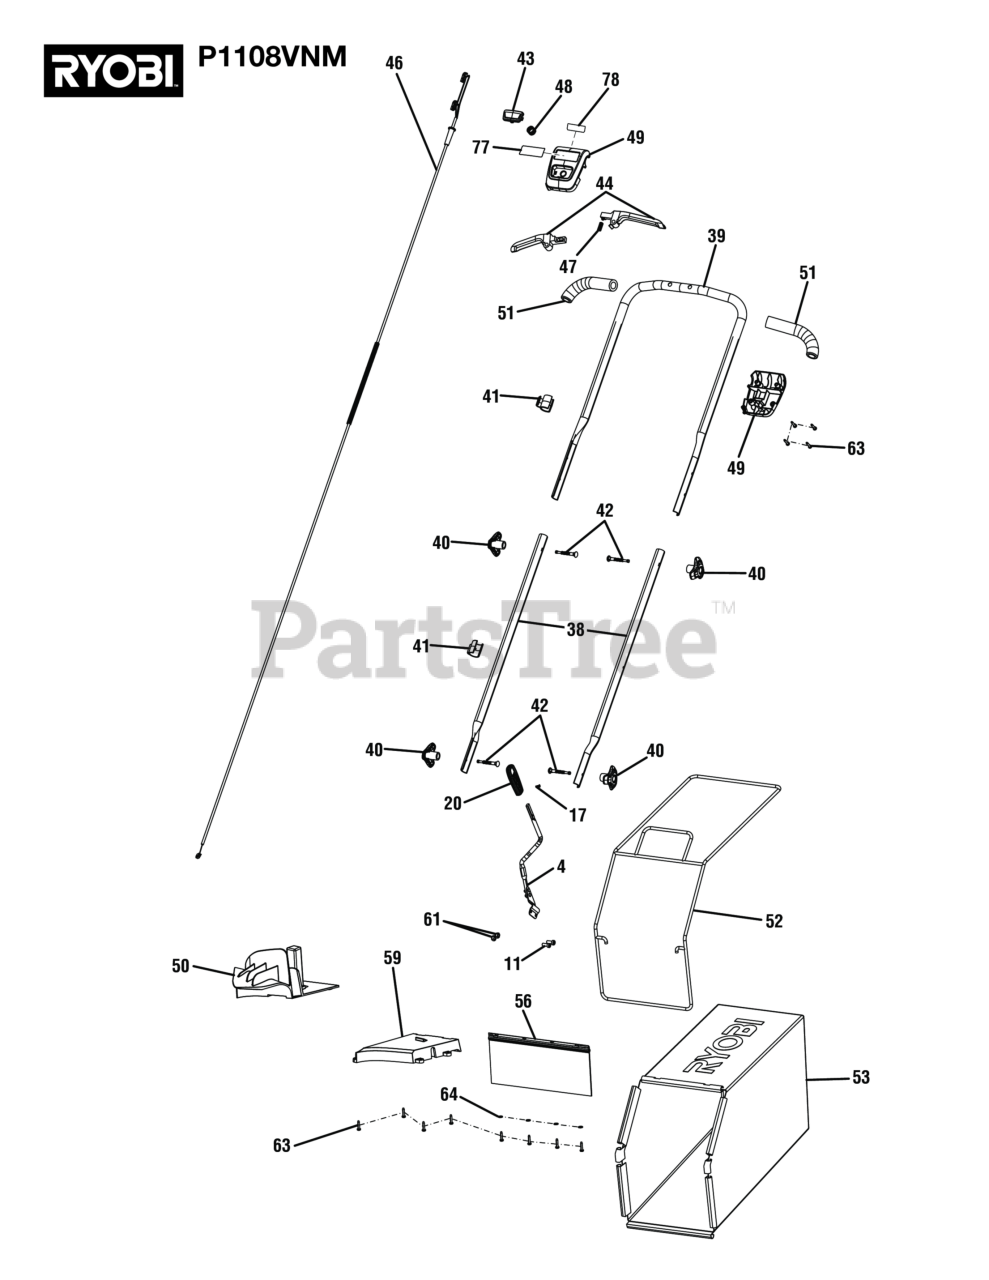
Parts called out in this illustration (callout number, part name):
4	Height Adjustment Rod
11	Screw (M6 x 14 mm, Hex Soc. Hd.)
17	Screw (M3 x 9 mm, Flat Hd.)
20	Height Adjustment Knob
38	Lower Tube
39	Upper Handle Tube
40	Wing Nut with Insert (M6)
41	Cable Clip
42	Shoulder Screw (M6 x 50 mm)
43	Safety Button
44	Trigger Assembly
46	Inner Wire and Plug Assembly
47	Compression Spring (Trigger)
49	Switch Box (Inc. Key Nos. 77-78)
50	Mulching Plug
51	Foam Tube
52	Grass Bag Frame
53	Grass Bag
56	Trailing Sheet
59	Discharge Baffle
61	Lock Nut (M6 x 6 mm)
63	Screw (M4 x 18 mm, T20 Torx Pan Hd.)
64	Washer (ID4.5 x OD10 x 1t)
77	Logo Label
78	Instruction/Logo Label
